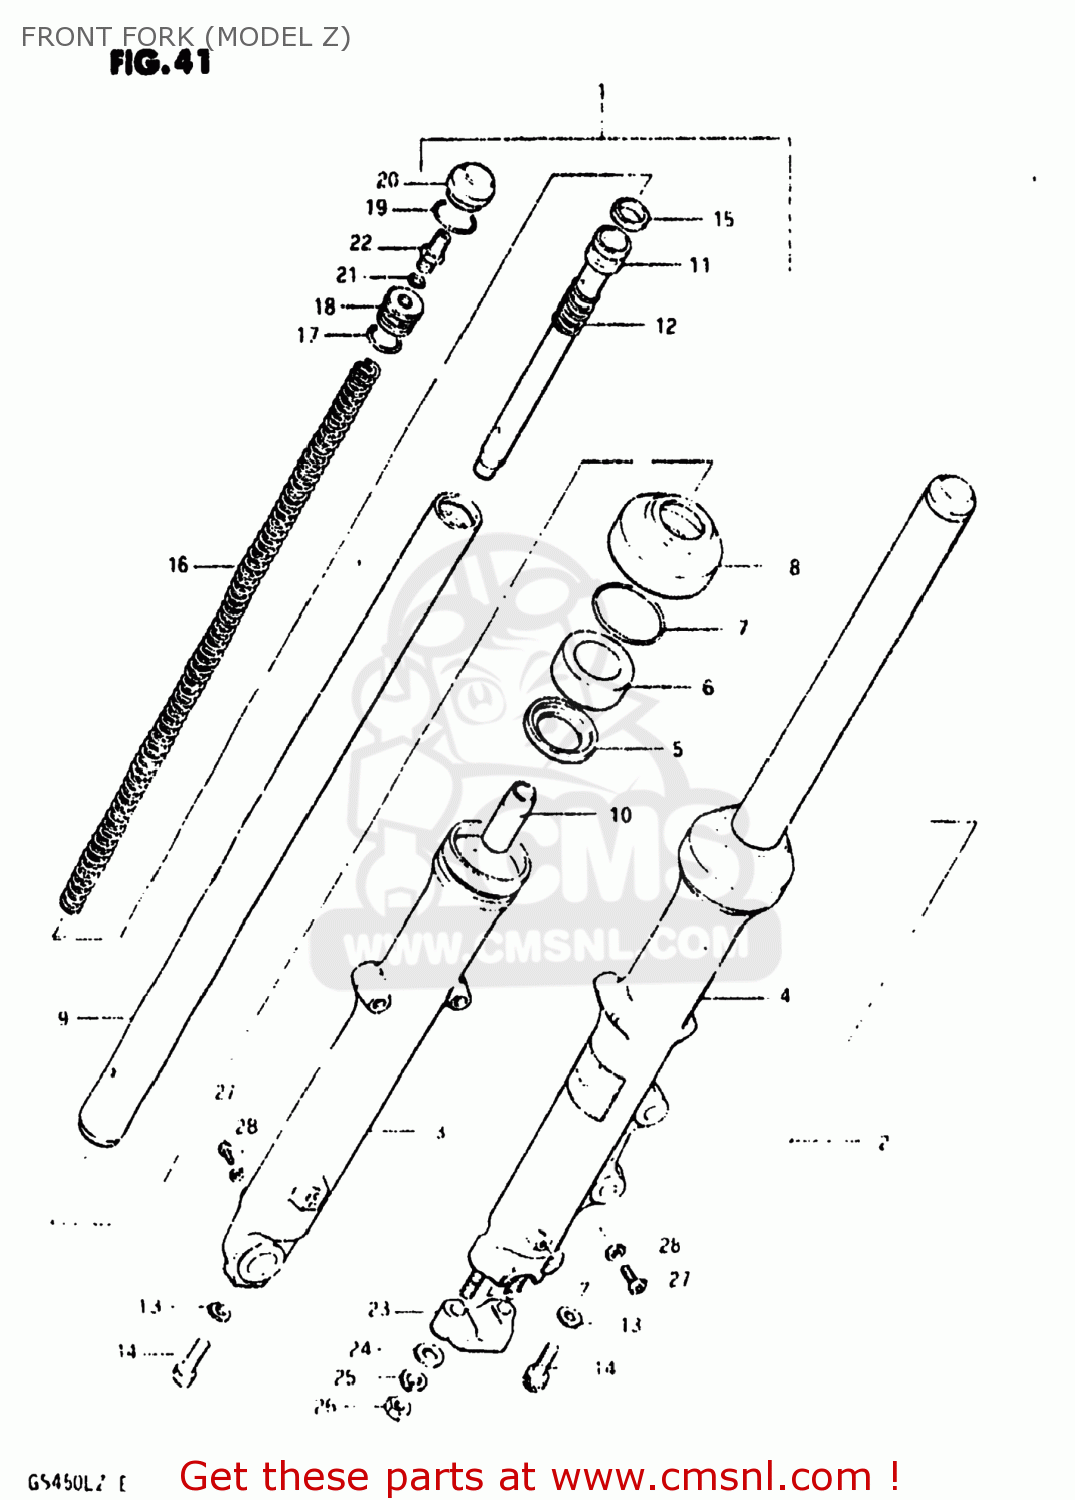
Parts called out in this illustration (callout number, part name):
1	DAMPER ASSEMBLY,RIGHT
2	DAMPER ASSEMBLY,LEFT
3	TUBE,FORK,OUTER,RIGHT
4	TUBE,FORK,LEFT,OUTER
5	SPACER,OIL SEAL
6	OIL SEAL,FRONT FORK
7	RING,OIL SEAL STOPPER
8	DUST SEAL
9	TUBE,FORK,INNER
10	PIECE,OIL LOCK
11	CYLINDER,FRONT FORK
12	SPRING,REBOUND
13	GASKET (NAS)
14	BOLT(8X27)
15	RING,PISTON
16	SPRING
17	O RING
18	SEAT,SPRING
19	RING,STOPPER
20	CAP,FRONT FORK
21	O-RING
22	VALVE,AIR
23	HOLDER,AXLE
24	WASHER
25	LOCK WASHER
26	NUT (8MM)
27	SCREW 4X6
28	GASKET (NAS)
